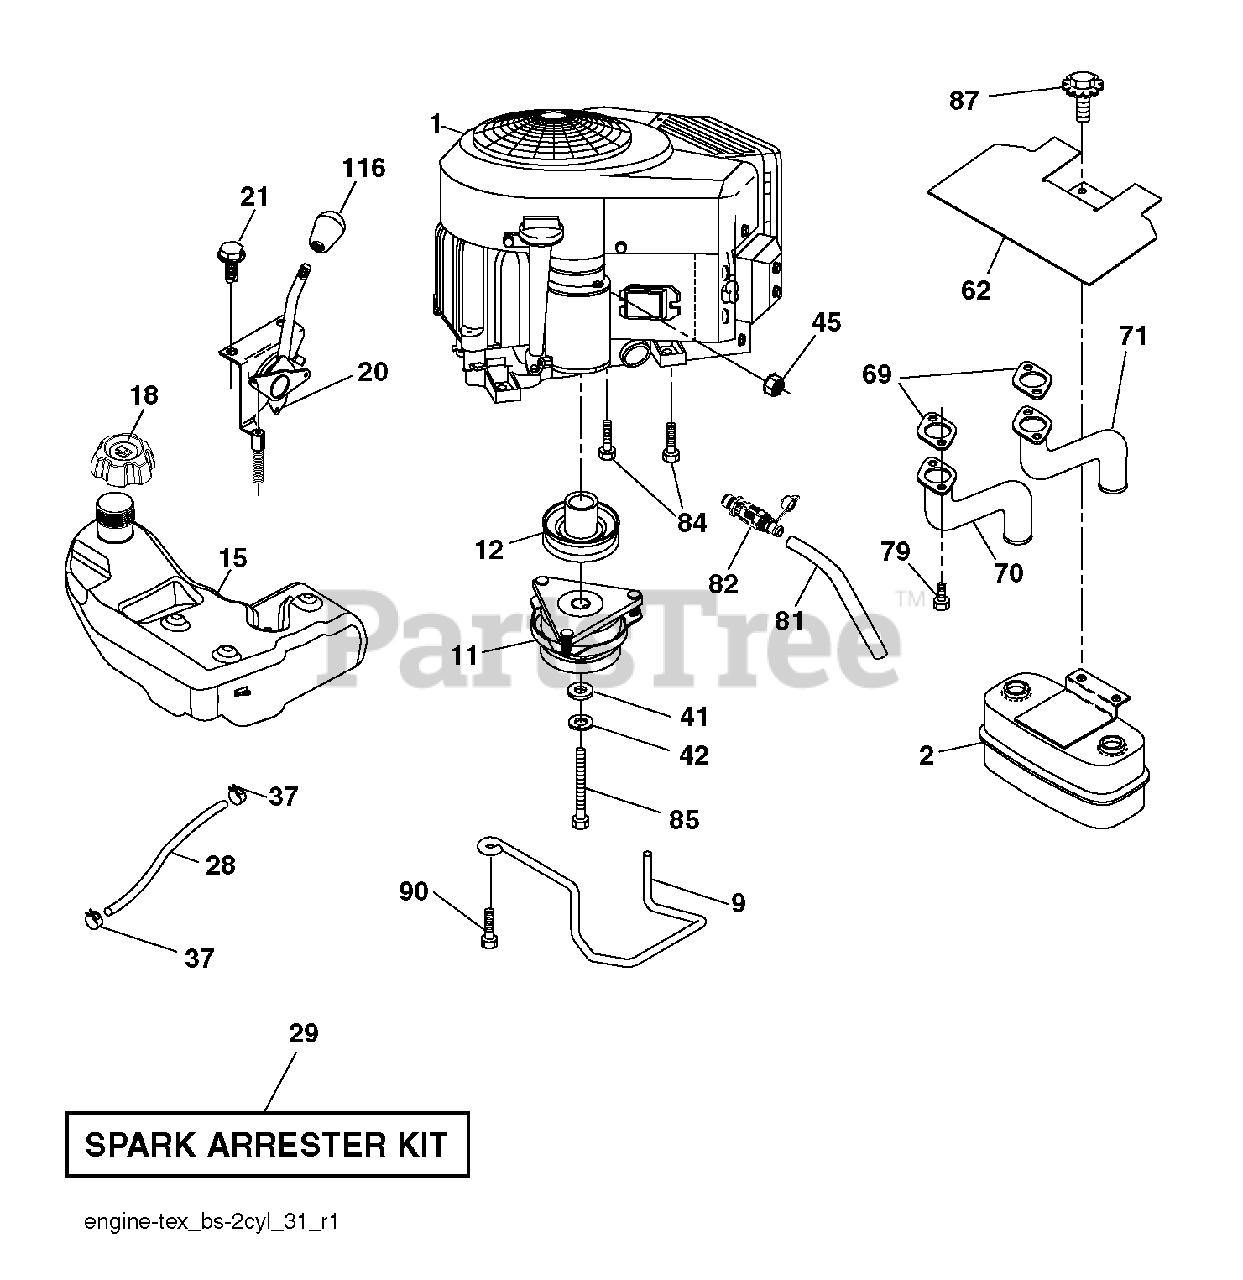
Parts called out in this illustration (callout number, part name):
2	MUFFLER.TWIN.CYL.LOW.TONE
9	KEEPER BELT ENGINE
11	CLUTCH ELECTRIC
12	PULLEY ENGINE
15	RP TANK.ASM.FUEL.4GA.CARB
18	CAP ASM.FL.RTCHT.3"GRY.E10
20	Throttle and Choke Control
21	SCREW.#10 X 0.750.BOS THREAD
28	LINE.FUEL.64"REAR.EMIS
29	ARRESTER SPARK (OPTIONAL)
37	HOSE CLAMP
42	LOCKWASHER
45	NUT
62	SHIELD.HEAT.MUFFLER
69	GASKET.MUFFLER
70	Exhaust Tube, LH.Bs/Twin
71	Exhaust Tube, RH B&S Twin Intek
79	SCREW.SOCKET.HEAD.5/16-18
81	TUBE, DRAIN OIL ASM.
82	VALUE.OIL.DRAIN
84	SCREW.3/8-16
85	BOLT HEX 7/16-20 X 3.75 GR. 5
87	BOLT.5/16-18UNCX1.W/SEMS.BLK
90	SCREW 3/8-16X1
116	KNOB - SHIFT
